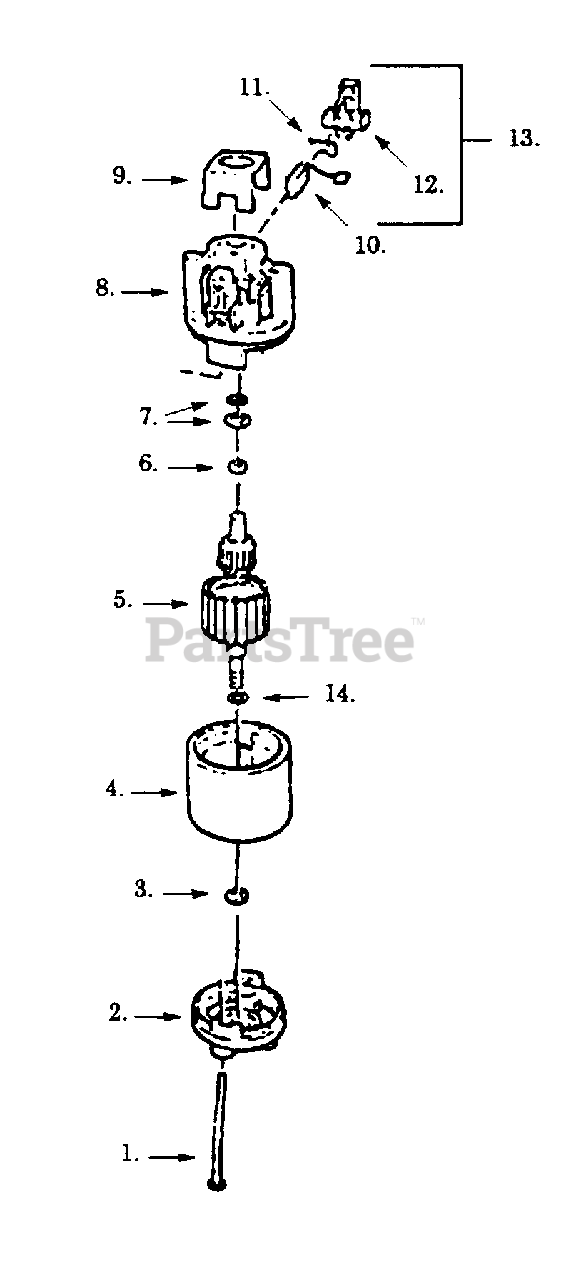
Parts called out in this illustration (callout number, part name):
2	Endbell Ass'y. (Drive)
4	Field Ass'y.
5	Armature Ass'y.
8	Endbell Ass'y. (Brush)
9	Insulator
10	Carbon Brush
11	Brush Spring
12	Brush Holder
13	Brush Kit (Incl. 10,11,12)
14	Retaining Ring
